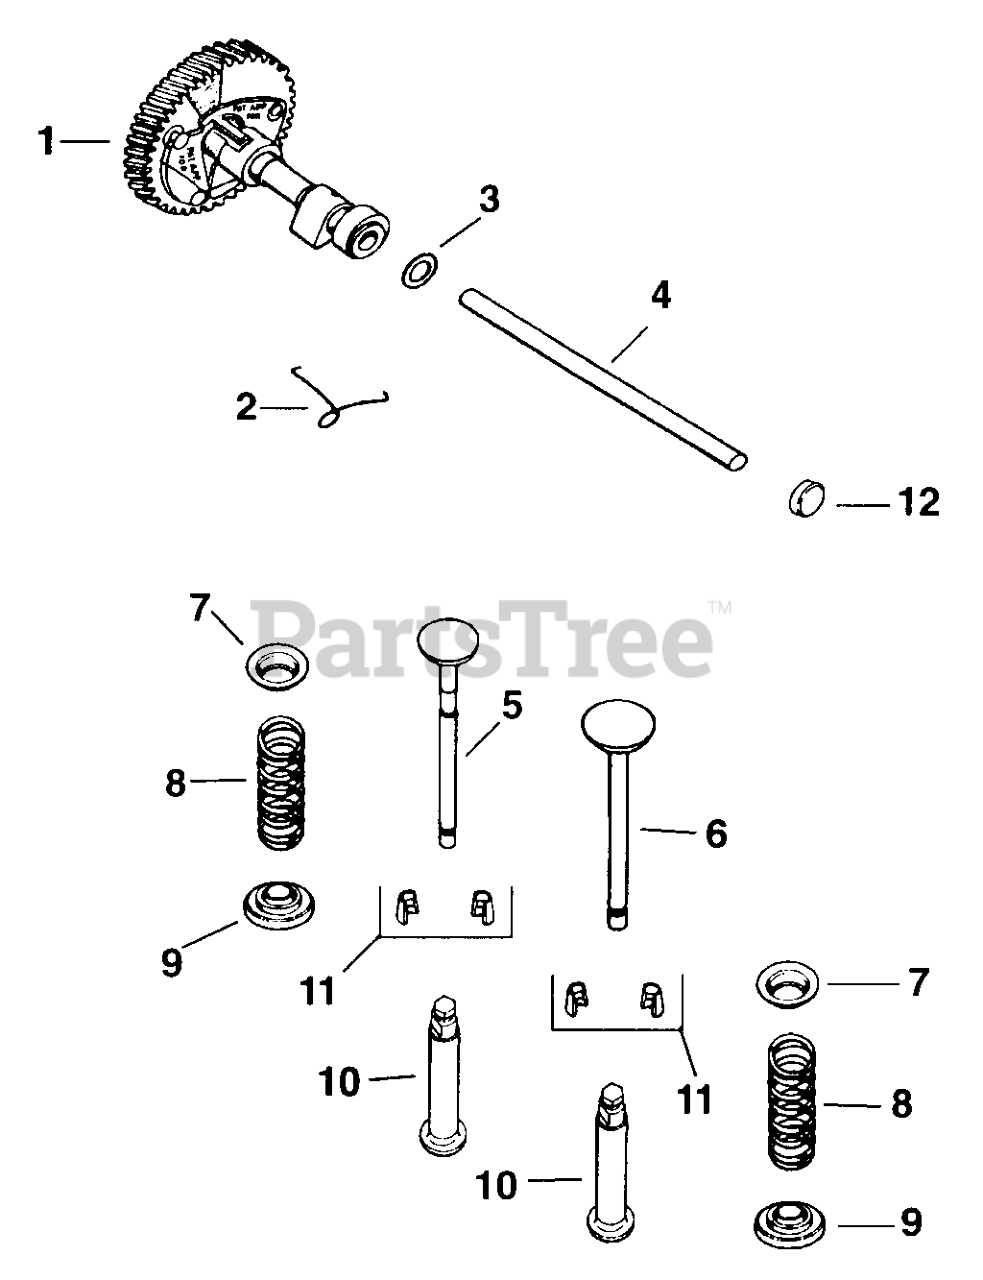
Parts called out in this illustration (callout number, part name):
1	CAMSHAFT - DISCONTINUED
2	SPRING, ACTUATING-DISCONTINUED
3	SPACER (.005")
3	SPACER (.010")
4	PIN, CAMSHAFT - DISCONTINUED
7	RETAINER, SPRING
8	SPRING, INTAKE VALVE - DISCONTINUED
11	KIT, RETAINER
12	PLUG, CUP 1/2" USE 25 139 50-S
